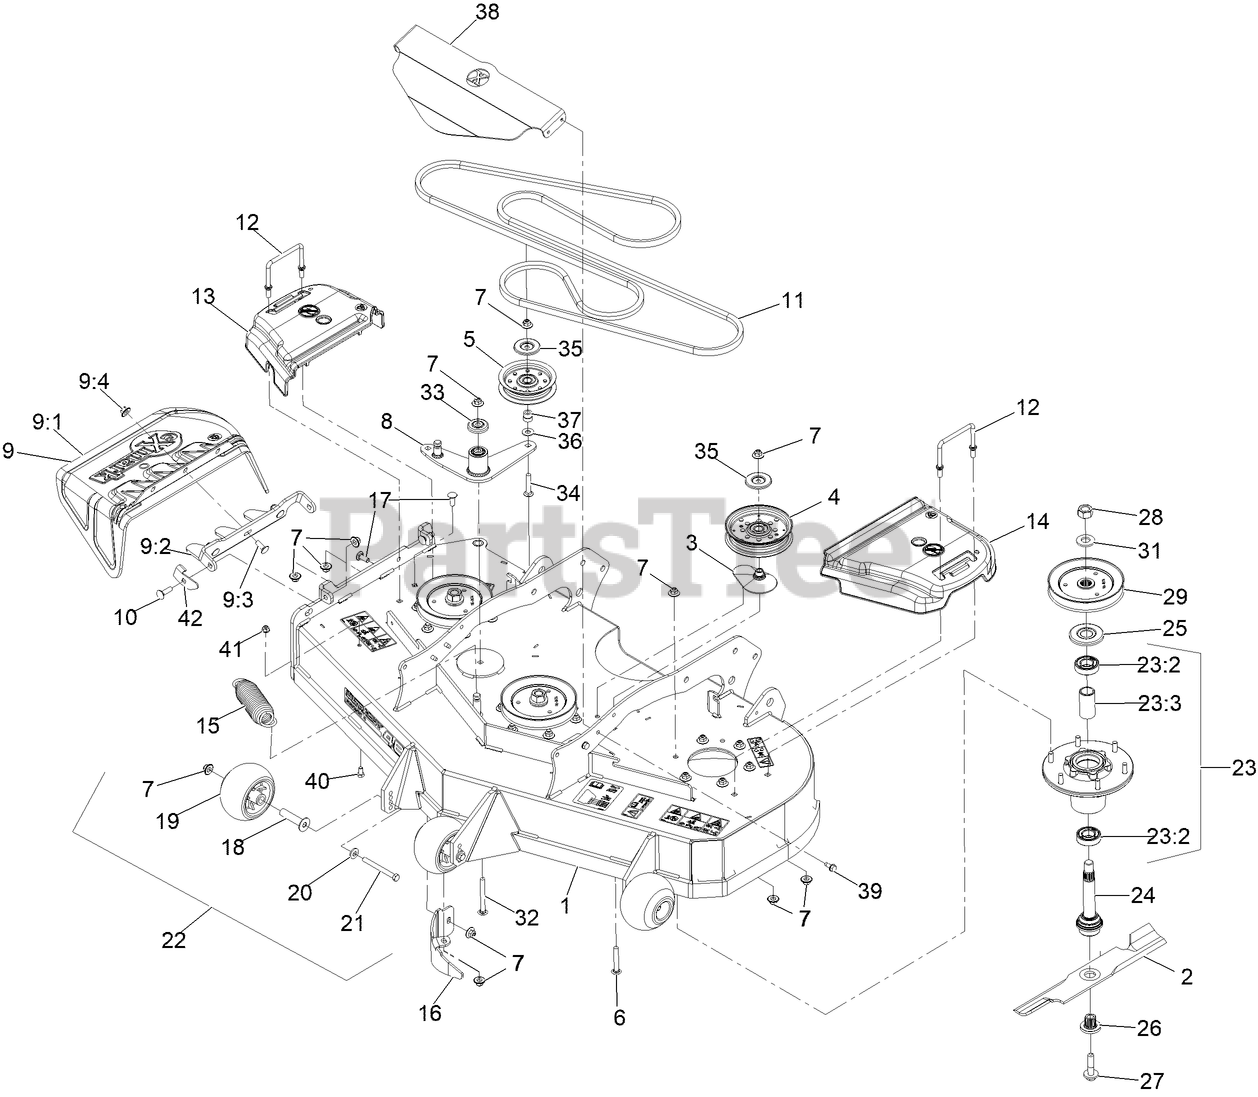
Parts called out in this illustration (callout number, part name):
1	ASM-DECK W/DECALS 484
3	SPACER-PULLEY
4	PULLEY-IDLER, FLAT
6	SCREW-CARR
7	Nut-Nyloc 3/8-16 Flg
8	IDLER ARM ASM W/BEARINGS
9	ASM,DISCHARGE CHUTE
9:1	CHUTE,DISCHARGE
9:2	BRACKET,DISCHARGE CHUTE
9:3	SCREW-CARR
9:4	Nut-Nyloc 3/8-16 Flg
10	BOLT-CARR
11	BELT-B147.4
12	WIREFORM-COVER
13	COVER-BELT, RH
14	COVER-BELT, LH
15	SPRING-EXTENSION
16	BAFFLE-DOGLEG,LZS LZX VT48
17	SCREW-CARR
18	AXLE, ROLLER
19	ROLLER-SCALP, ANTI
20	WASHER-BELLEVILLE
21	SCREW-HH 3/8-16 X 3 3/4 GR 8
22	KIT, ANTI-SCALP ROLLER
23	ASM-CUTTER HSG WITH BEARINGS
23:2	BEARING-BALL
23:3	SPACER-BEARING
24	ASM-SPINDLE AND SEAL
25	GUARD,BEARING TOP .989
26	BUSHING,SPLINED
27	SCREW,SEMS 1/2-20 X 2.19
28	NUT-HEX
29	SHEAVE,BLADE DRIVE 5.90
32	SCREW-CARR
33	GUARD-TOP
34	SCREW-CARR
35	SHIELD-DUST
36	WASHER-FLAT
37	BUSHING,IDLER
38	Guard-Front Deck
39	SCREW-THD ROLL, HWH
40	SCREW-HH
41	NUT-HF, NI
42	STOP-DISCHARGE CHUTE
